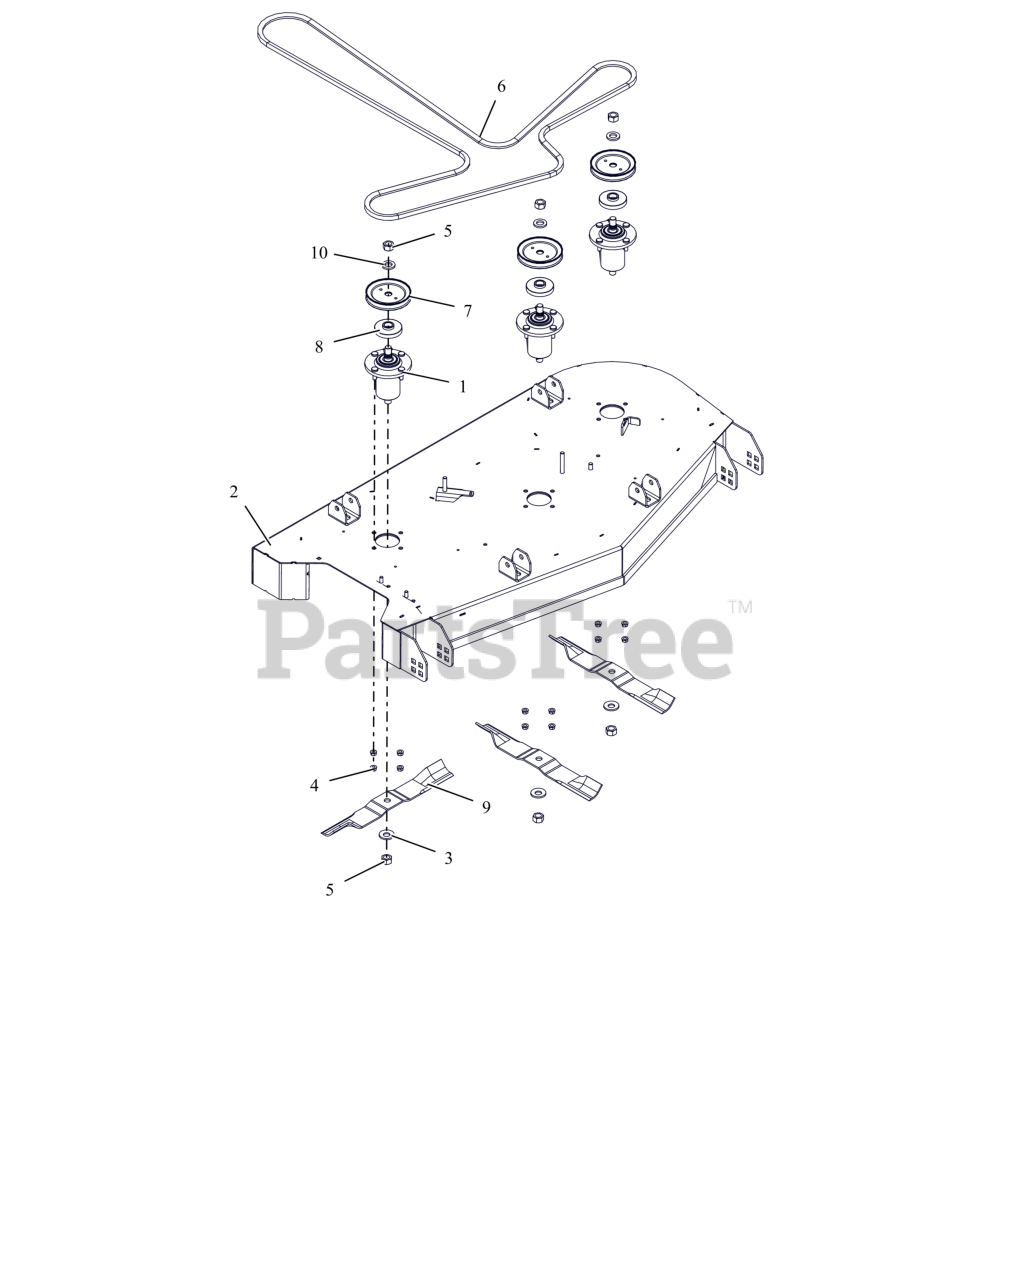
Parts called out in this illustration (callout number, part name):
1	ASM, ALUMINUM SPINDLE SUB
2	KIT,ARIENS DECK 48" WITH DECALS
3	WSHR-BLVL .669X1.535X.138
4	NUT,LK-CTR-FLG .31-18 GF ZCC
5	NUT-STD .625-18 ZCC
6	V-BELT, HA SECTION
7	PULLEY, V-4.50 ODX.625 SPLINE ID
8	SHIELD, DUST
9	BLADE, MOWER 16.50"
